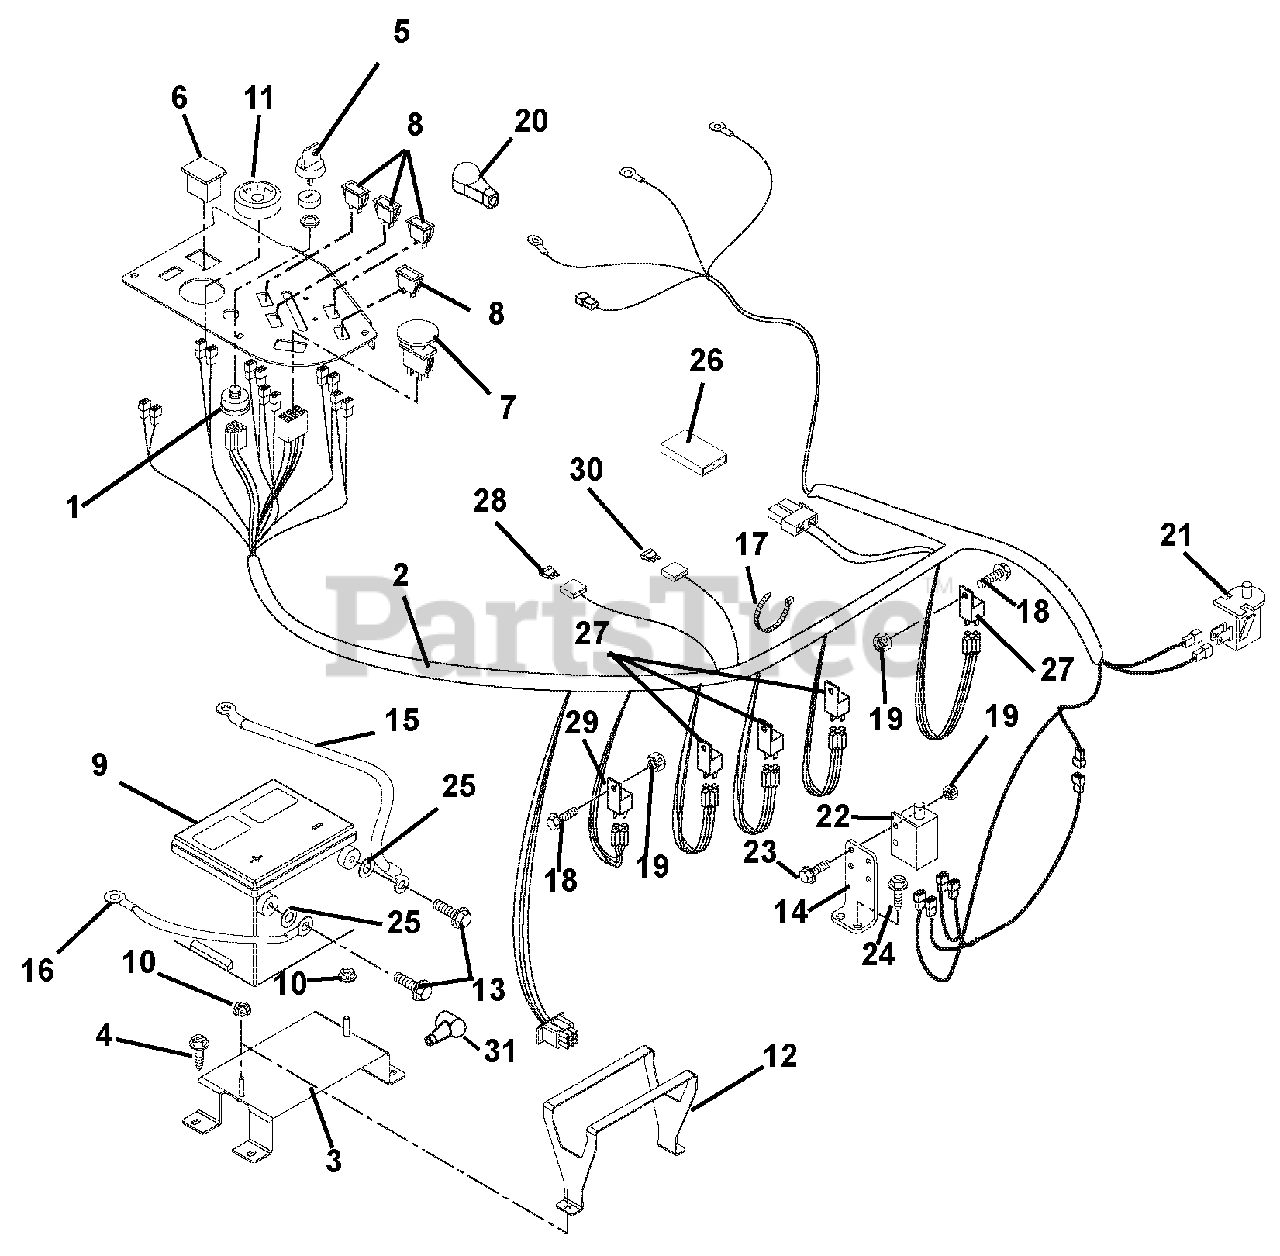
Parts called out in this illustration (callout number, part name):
1	SWITCH, IGNITION
2	HARNESS-WIRE PM200 HORIZ. L/C
3	WMT, BATTERY SUPPORT
4	@SCR-TAP .38-16X.75 HWH TR YWZ
5	KEY, W/ SHIELD
6	METER, HOUR W/MAINTENANCE
7	SWITCH, CLUTCH
8	LIGHT,INDICATOR
9	BATTERY-GROUP 70-540 CCA
10	@NUT-LK-TOP-FLG .31-18 YWZC
11	GAUGE, TEMPERATURE
12	BRACKET-BATTERY HOLD-DOWN
13	BATT TERMINAL SCREW
14	MOUNT, SAFETY SWITCH
15	CABLE - POS BATT W/BOOTS 4X48
16	CABLE, NEGATIVE BATTERY 49.00
17	CABLE TIE LG 5-1/2
18	@SCR-MCH 10-24X.75 HWH YWZC
19	@NUT-LK-NYL 10-24 W/INSRT YWZC
20	BOOT, TERMINAL, RED
21	SWITCH- SNAP MTG N.O.
22	SWITCH- DOUBLE POLE N.O./N.O.
23	@SCR-MCH 10-24X.75 HWH YWZC
24	@SCR-TAP .25-20X.50 HWH TR YWZ
25	@WSHR-FL-STL.38X.875X.083 YWZC
26	DIODE, CONNECTOR SHELL
27	RELAY,SEALED W/DIODE
28	FUSE, ATO 30 AMP
29	Pre-Heat Timer (Included with Engine)
30	FUSE, ATO 60 AMP
31	BOOT, BATTERY TERMINAL-RED
